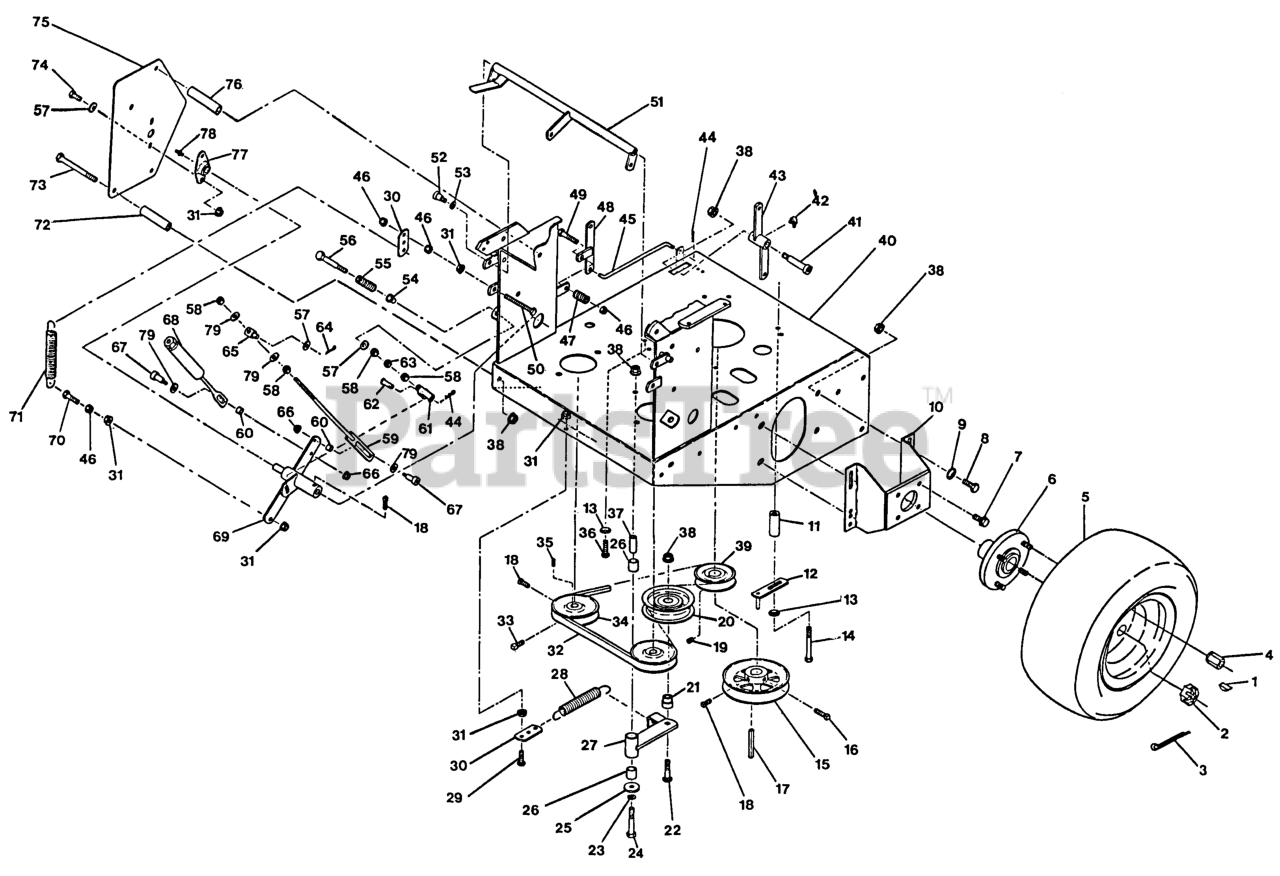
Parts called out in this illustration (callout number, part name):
1	KEY-WOODRUFF
12	GUIDE-BELT
13	WASHER-SPRING
17	KEY,MACH 1/4X1/4X2-5/8
18	SCREW-SET
19	SCREW-SET
21	BUSHING-IDLER
26	SLEEVE-BEARING
27	IDLER ARM ASM
28	SPRING-EXTENSION
30	ANCHOR-SPRING
32	BELT,HYDRO TRANS DRIVE
34	SHEAVE - PUMP
37	BUSHING
44	PIN-COTTER
45	LINKAGE-ENGAGE, BLADE
50	BOLT,TAP HH
52	SCREW-HSH
54	BUSHING-FLANGED
55	SPRING-RETURN, NEUTRAL
56	BOLT-RETURN, NEUTRAL
61	YOKE-ADJUSTABLE
62	PIN-CLEVIS
67	SCREW-HSH
69	WLD,HYDRO CONTROL ARM LH
71	SPRING-EXTENSION
72	SPACER-SHIELD
76	SPACER-SHIELD
77	FLANGE MTG, SIDE
